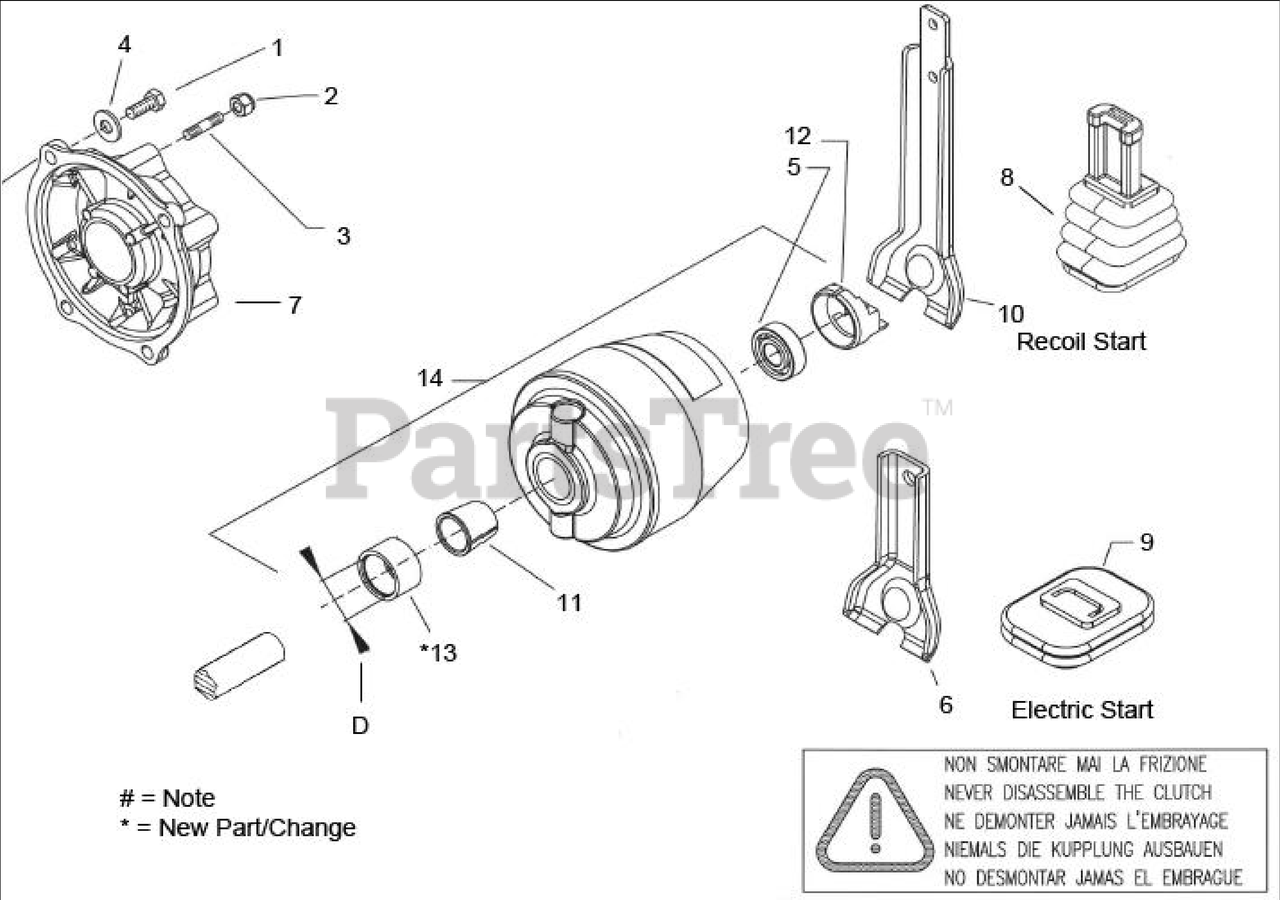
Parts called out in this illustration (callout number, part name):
1	CAPSCREW 3/8-16 X1
2	LOCKNUT M8 SELF LOCKING
3	STUD M8X40X14X14
4	WASHER LOCK M10.4
5	BEARING 17x40x12 6203 2RS/C3 SKF
6	CLUTCH FORK (Electric Start)
7	FLANGE, ENGINE
8	BOOT/BELLOWS (Recoil Start)
9	BOOT/BELLOWS (Electric Start)
10	CLUTCH FORK ( Recoil Start)
11	TAPERED BUSHING D=25.4mm
12	PUSHER CONE
13	SPACER 18mm D=25.4mm
14	CLUTCH (Includes #13,11,5 &12 )
